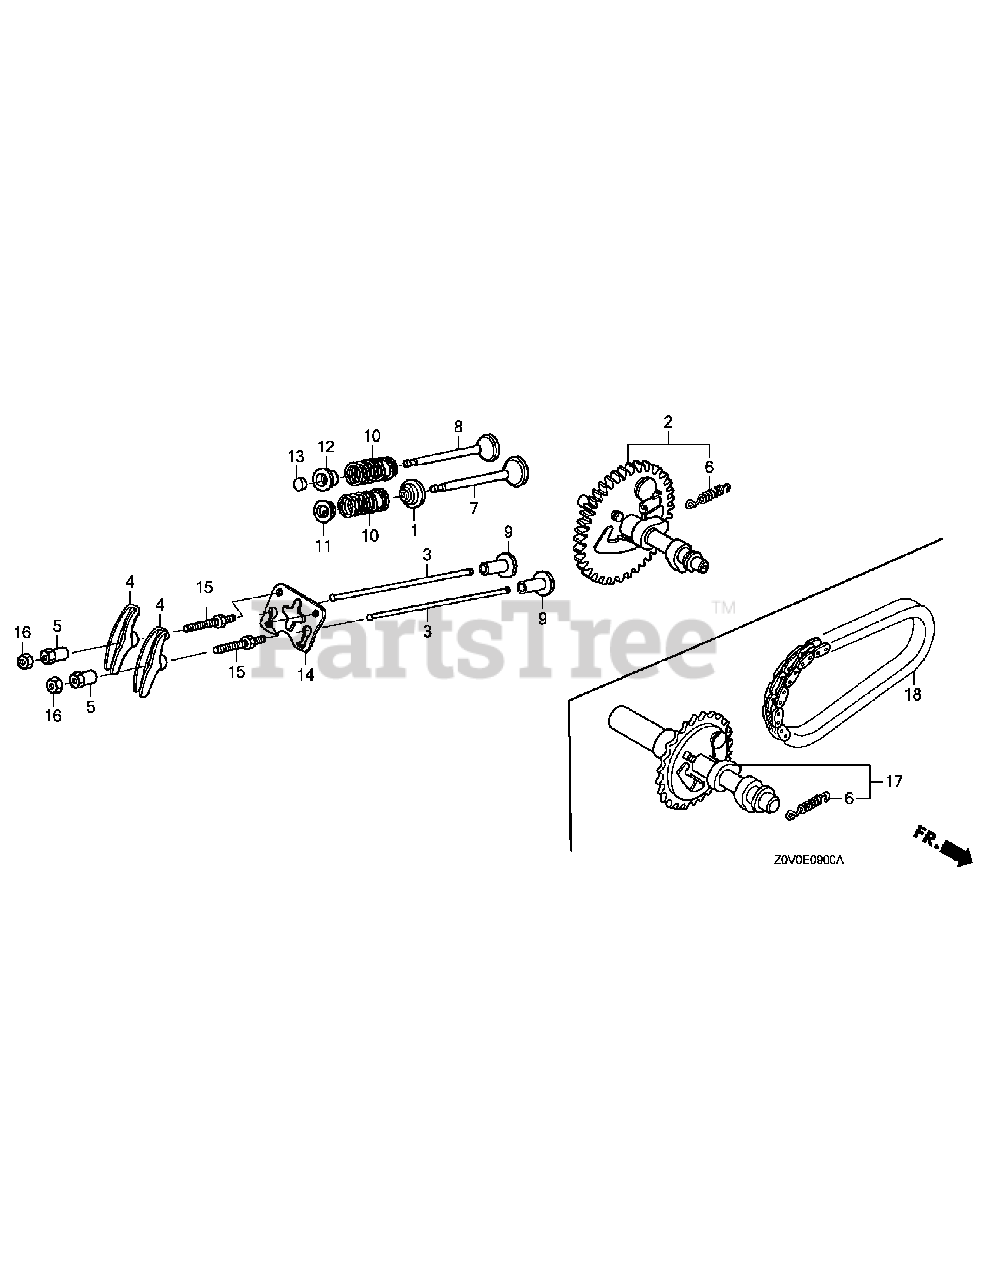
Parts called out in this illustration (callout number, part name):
1	Seal, Valve Stem
2	Camshaft Assy.
4	Arm, Valve Rocker
5	Pivot, Rocker Arm
6	Spring, Weight Return
7	Valve, In.
8	Valve, Ex.
9	Lifter, Valve
10	Spring, Valve
11	Retainer, In. Valve Spring
12	Retainer, Ex. Valve Spring
13	Rotator, Valve
14	Plate, Push Rod Guide
15	Bolt, Pivot, 8Mm
16	Nut, Pivot Adjusting
17	Camshaft Assy.
18	Chain, P.T.O. Drive
